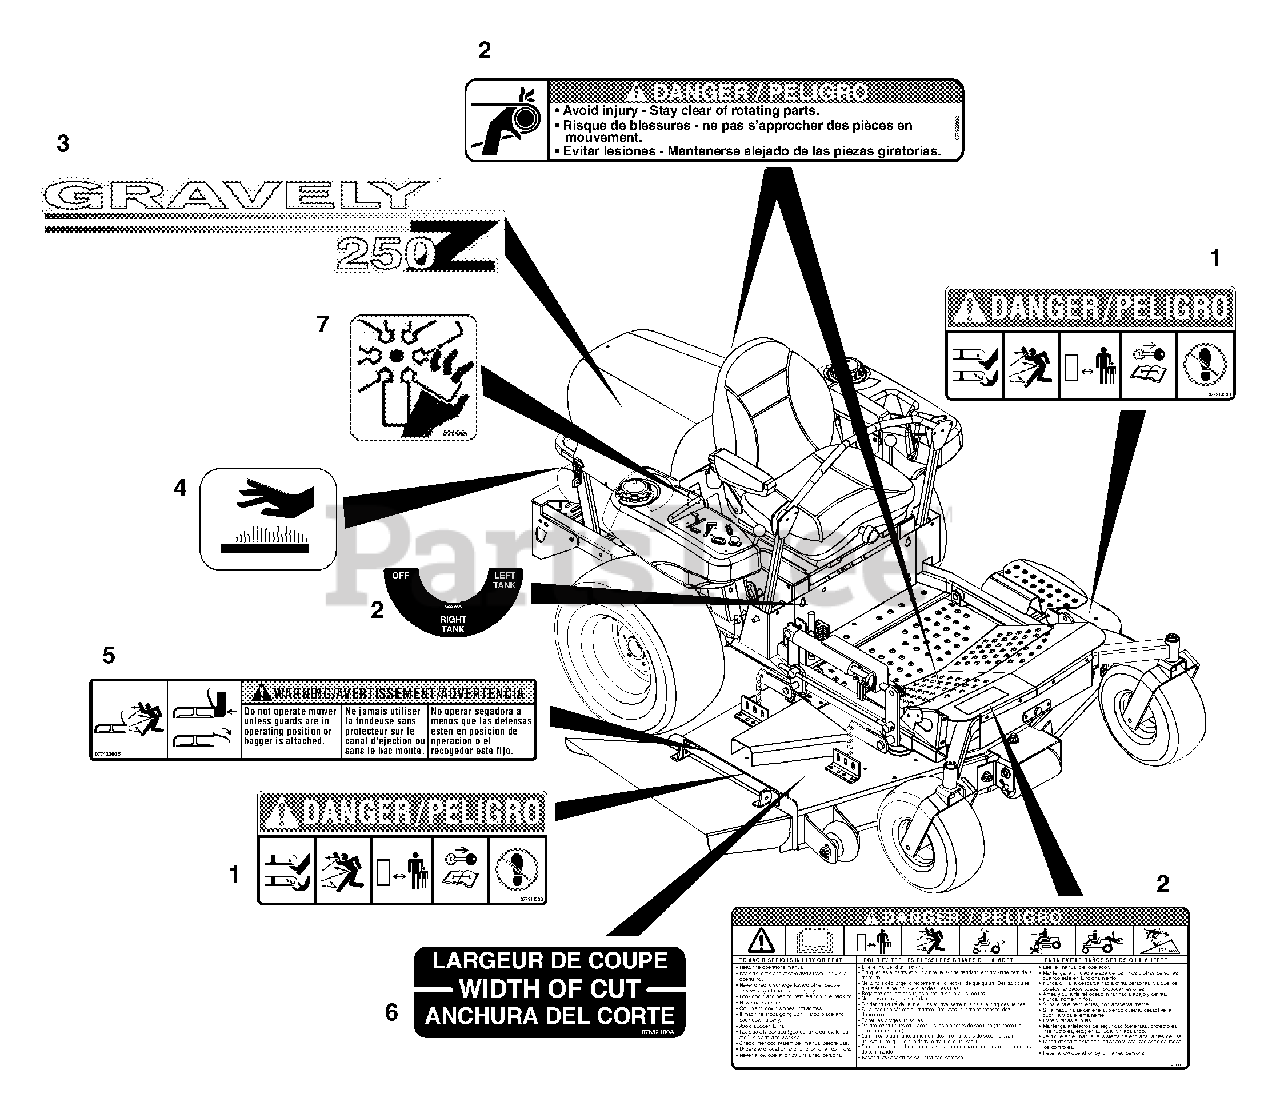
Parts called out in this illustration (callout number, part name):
1	Decal, Mower Pan Head Danger
2	Set, Decal-Common Danger/Fuel
3	Decal, PM-250Z Hood (034, 035)
3	Decal, PM-260Z Hood (020, 029, 033)
3	Decal, PM-272Z Hood (030, 032)
4	Decal-Hot Surface
5	Decal, Warning
6	Decal, Width of Cut
7	Decal, Danger Fan
